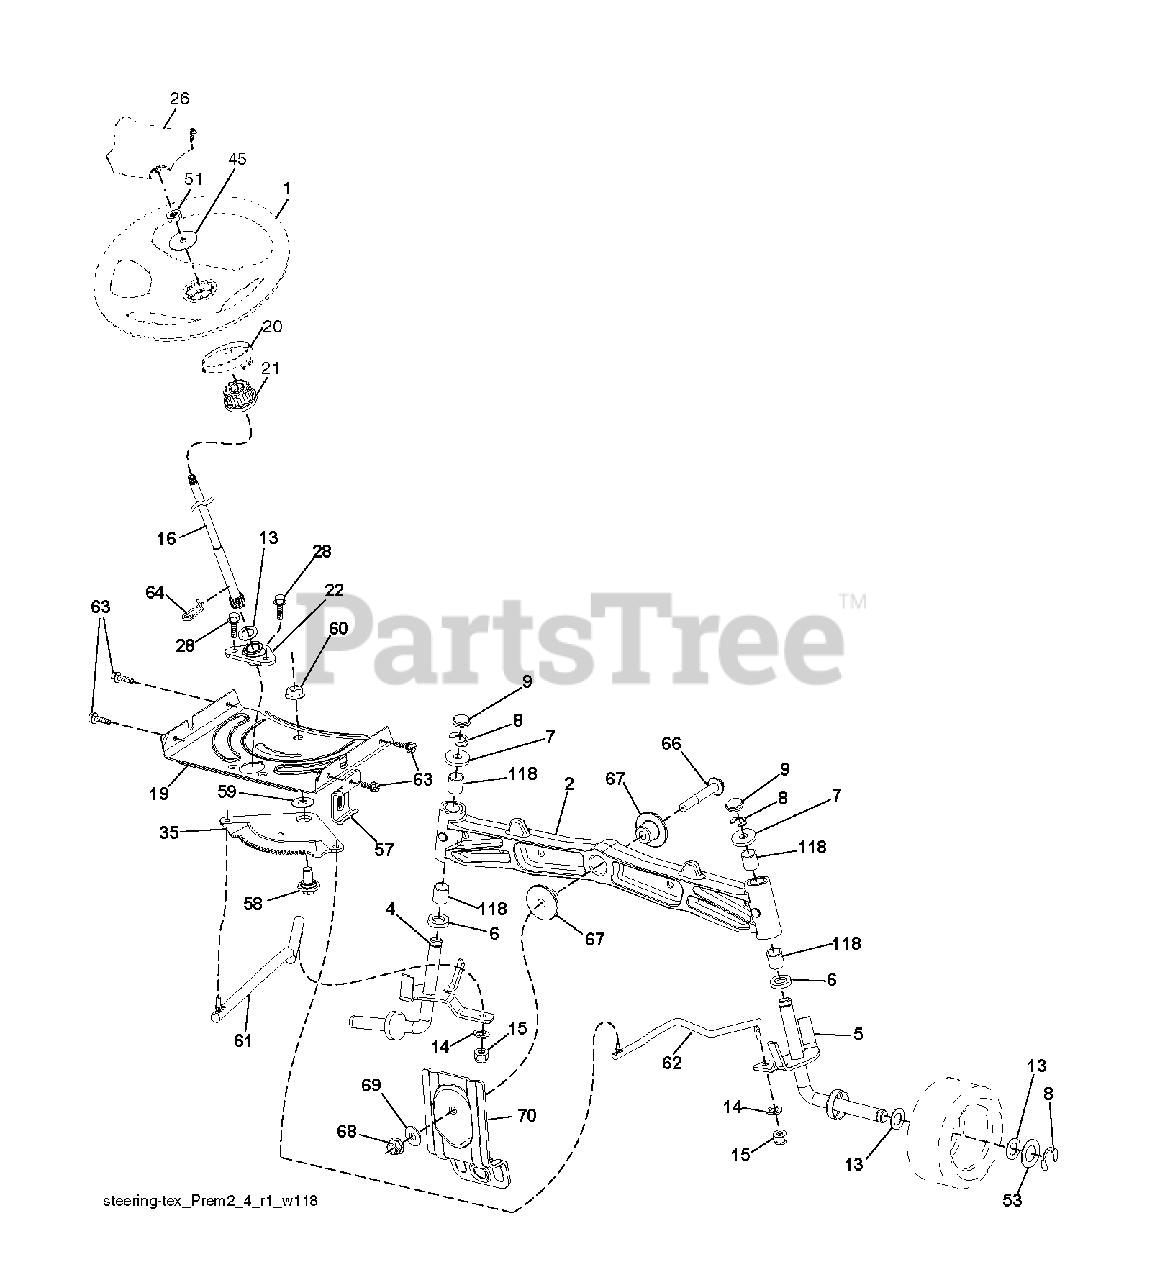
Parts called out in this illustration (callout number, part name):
1	WHEEL.STEERING.PREM.2.BLK
2	AXLE.SVC.ASM CAST IRON.TEX
4	SPINDLE.WELDED.LH.16"TEX
5	SPINDLE.WELDED.RH.16"TEX
8	RING CLIP
9	CAP.SPINDLE
14	WASHER, LOCK 3/8
15	NUT CROWNLOCK 3/8-24
16	SHAFT.STEER.STEALTH.DD
19	PLATE.STEER.DDL.NLT/NG
21	ADAPTER, WHEEL STNG..
22	STEERING.SUPT.LOWER.
26	INSERT.CAP.STRG.WH.BLACK
28	SCREW, 3/8-16X3/4
35	GEAR.SECTOR.PLATE.DDL.
45	WASHER 9/16"ID, 2 3/8"OD
51	NUT.HEX.1/2-20
53	WASHER.HARDENED
57	BRKT.UPSTOP.GT/LT.TEX
58	BOLT.SHOULDER.SECTOR.P
59	WASHER.THURST.SECTOR.S
60	NUT FLANGE LOCK 5/8-11
61	DRAGLINK.LH.BALLSTUD.D
62	DRAGLINK.RH.BALLSTUD.D
63	SCREW
64	RETAINER.CLIP.SPRING.S
66	BOLT HEX FGHD 7/16-14 X 3 SERR
67	BUSHING.PM.FRONT AXLE
68	NUT.LOCK.FLANGE.7/16
69	WASHER.1.5X.505X.118
70	BRKT.DECK.SUSPENSION.F
118	BUSHING, AXLE CAST
